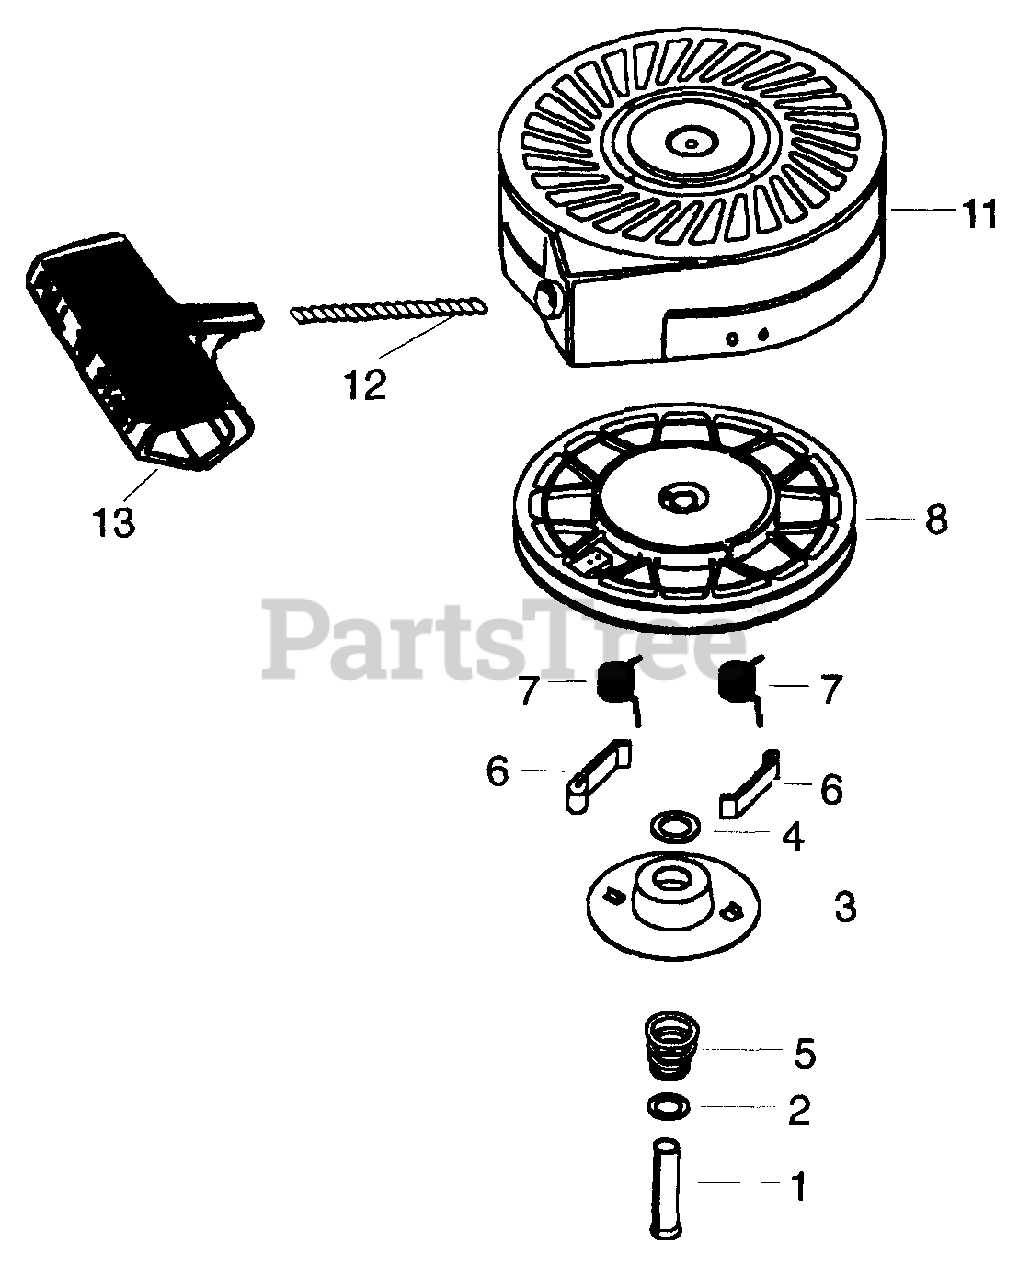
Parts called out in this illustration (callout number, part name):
5	Brake Spring
6	Starter Dog
7	Dog Spring
8	Pulley & Rewind Spring Assy
11	Starter Housing Assy
12	Starter Rope
13	Starter Handle
